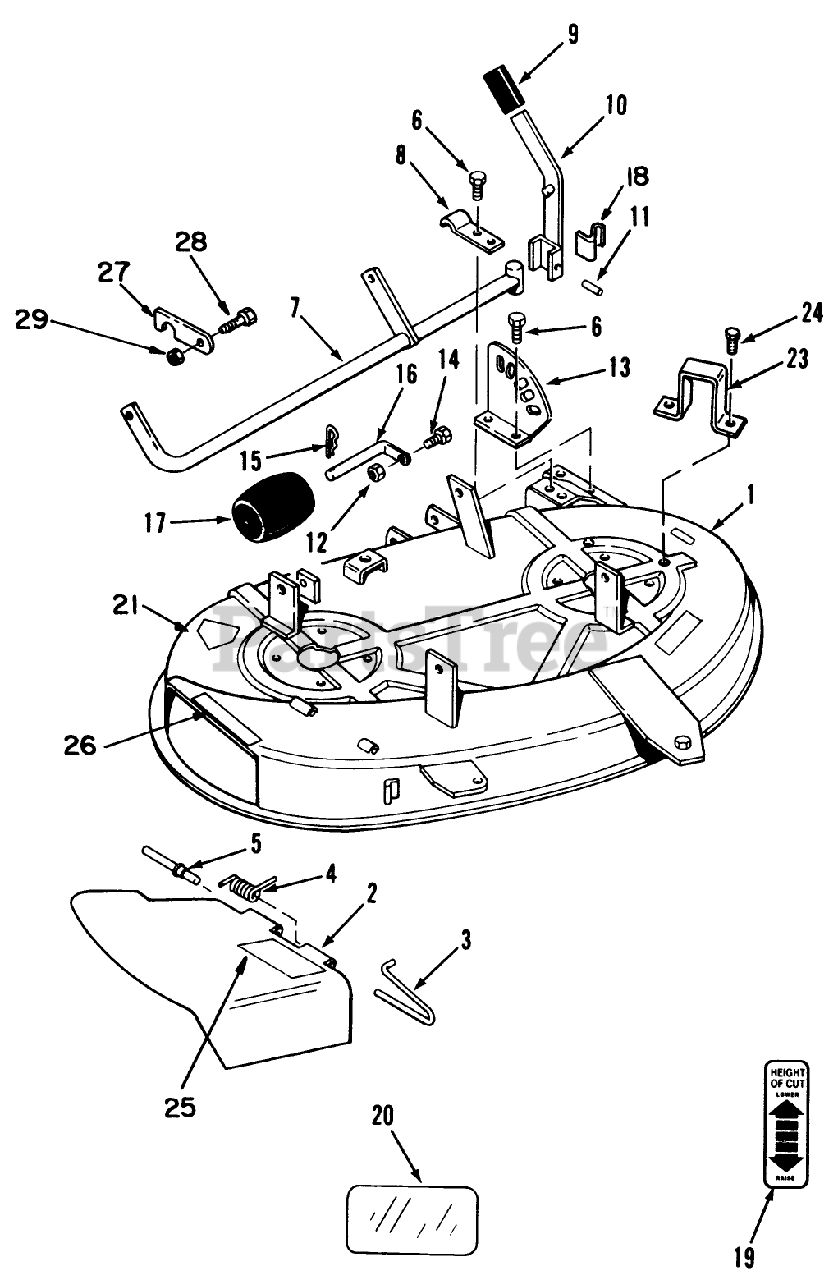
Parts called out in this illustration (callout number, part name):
1	Deck-Mower
2	Chute-Discharge
3	ROD-HINGE FRONT
4	SPRING-TORSION
5	ROD-HINGE REAR
6	Bolt
7	Shaft-Lift
8	Bracket-Pivot
10	Lever
11	SPIROL PIN 3/8X1 1/2
12	Nut
13	Quadrant
14	Bolt
15	Cotter Pin
16	SHAFT-ROLLER
17	ROLLER
18	CLIP-SPRING
19	DECAL-HOC
20	DECAL-OVERLAY
21	DECAL-DANGER
23	STOP-DECK R
24	Screw
25	DECAL-DANGER, THROWN OBJECT
26	DECAL-DANGER
27	Lock-Shaft
28	BOLT
29	NUT
